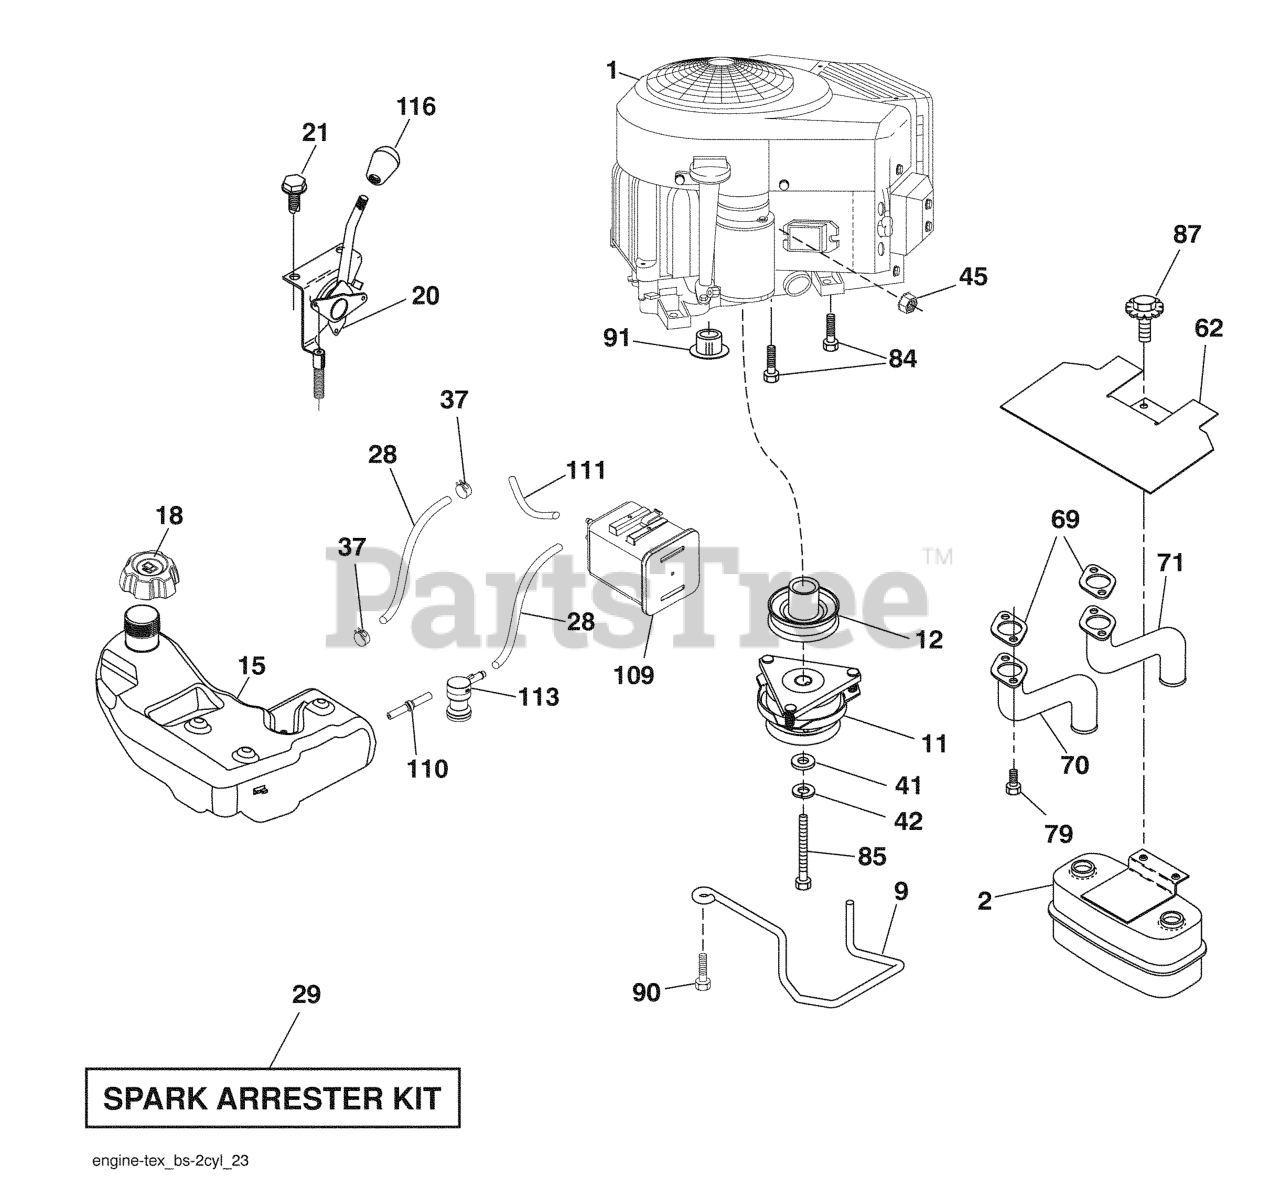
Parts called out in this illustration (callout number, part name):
2	MUFFLER.TWIN.CYL.LOW.TONE
9	KEEPER.BELT.ENGINE.4.2
11	CLUTCH.ELECTRIC.LT.48"*
12	PULLEY.ENGINE.TUFFTORQ
15	TANK.ASM.FUEL.3GA.CARB
18	CAP ASM
20	CONTROL THROTTLE/CHOKE
21	SCREW.#10 X 0.750.BOS
28	LINE.FUEL.64"REAR.EMIS
29	KIT.SPARK ARRESTOR 794945 B&S
37	HOSE CLAMP
42	LOCKWASHER
45	NUT
62	RP SHIELD HEAT MUFFLER
69	GASKET.MUFFLER
70	RP.EXHAUST.TUBE.LH.BS/TWIN
71	EXHAUST.TUBE.RH.BS/TWIN
79	SCREW.SOCKET.HEAD.5/16-18
84	SCREW.3/8-16
85	BOLT HEX 7/16-20 X 3.75 GR. 5
87	BOLT.5/16-18UNCX3/4 W/SEMS.BLK
90	SCREW 3/8-16X1
91	BUSHING.1.375OD
109	CANNISTER, CARBON
110	VALVE.ASM.ANTI-SLOSH
111	RP PURGE LINE
113	VALVE.SLANT.CARTRDG.90 DEG.TEX
116	RP KNOB SOFT TOUCH
